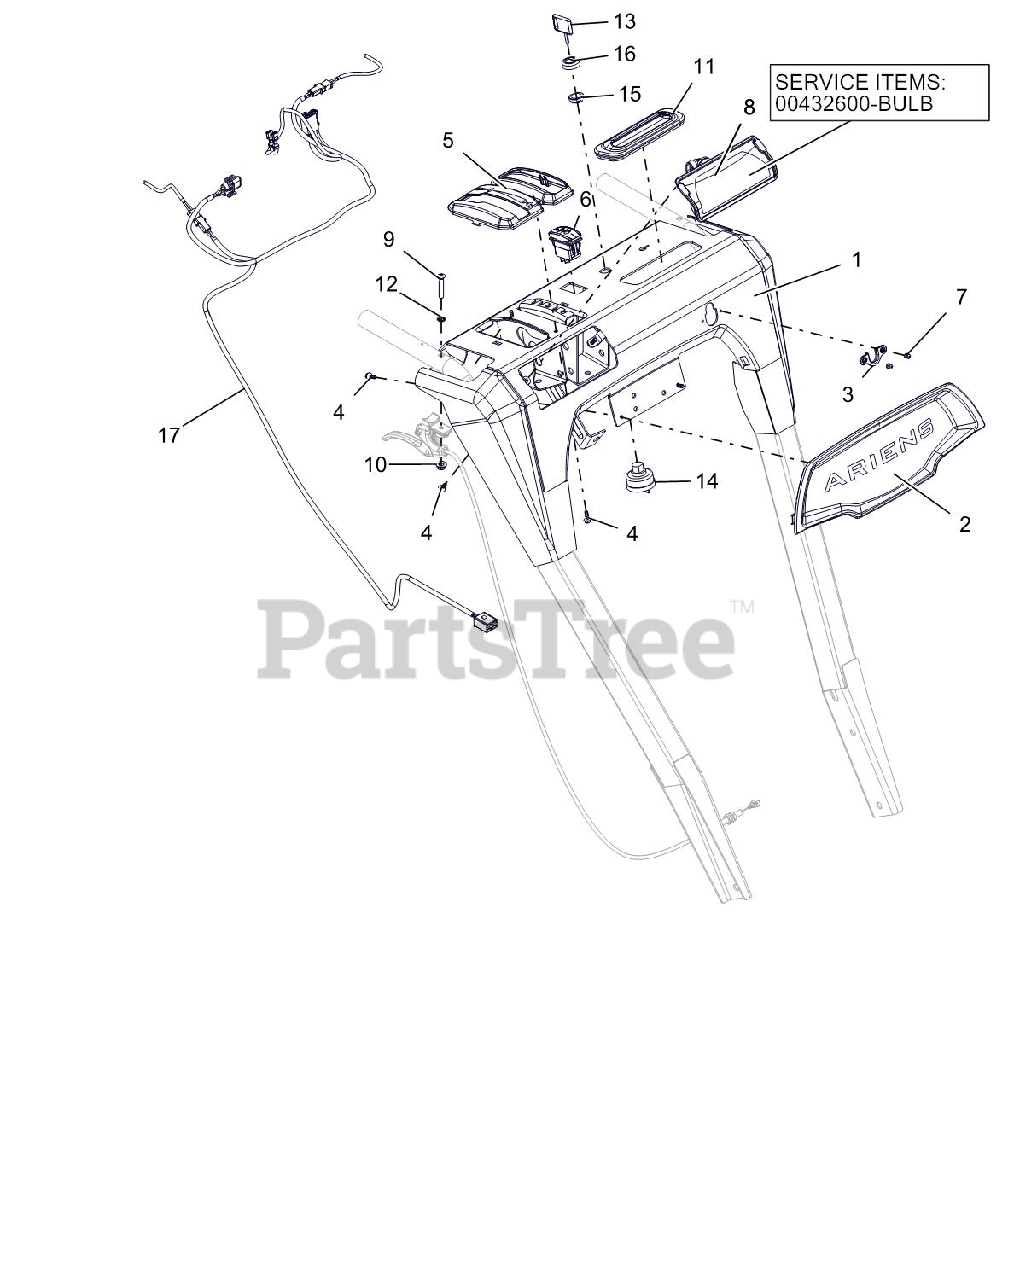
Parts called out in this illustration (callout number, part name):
1	PANEL, DASH-HYDROTRACK W/DECAL
2	BEZEL, DASH - ARIENS LG DASH
3	GROMMET, CABLE, QUICK TURN 2
4	SCR-TAP #10X.50 BOSS INDHXHD
5	BEZEL, SHIFT - HYDRO SNOW
6	SWITCH,ROCKER SPST-ON/OFF
7	RVT-POP #43 .125X.313 STL ZINC
8	BULB, LIGHT-HALOGEN 20W
8	HEADLIGHT ASY, HALO 20W 2SHOT
9	SCR-MCH .25-20X1.50 OVAL HD
10	@NUT-LK-CTR-FLG .25-20 YWZC
11	GROMMET, BOOT, QUICK TURN
12	WSHR-LK-INT .250 TH TYA
13	KEY -W/CAP
14	IGNITION SWITCH ASSEMBLY
15	NUT-PANEL .625-32 GRECO
16	CAP - IGNITION SWITCH
17	HARNESS,ELEC - HANDLEBAR 12V
